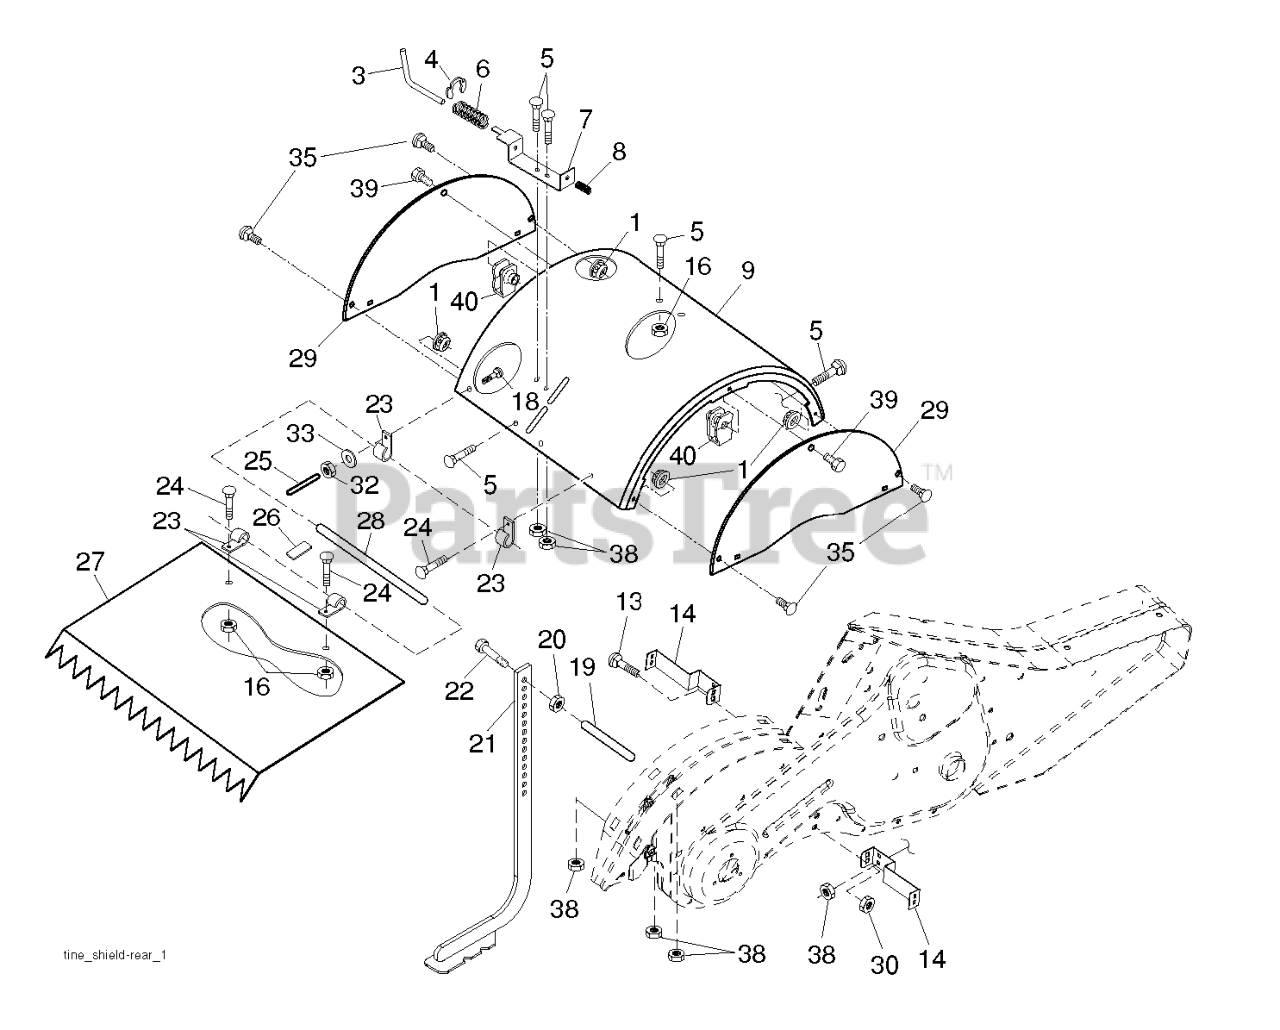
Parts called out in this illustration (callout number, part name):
1	NUT.FLANGE.5/16
3	STAKE PIN TI
4	RING, KLIP
5	BOLT, RDHD SQNK 5/16-18 X 3/4
7	BRACKET
8	SPRING CRT
9	SHIELD.TILLER.TINE.CRT14.ORNG
13	BOLT.CARRIAGE.5/16-18
14	BRACKET.TINE.SHIELD.BLACK
16	NUT T
20	NUT.HEX.3/8-16UNC
21	REPL BY 532 10 21-56
22	BOLT.375-16
25	VINYL CAP TI
26	PAD IDLER TI
27	SHIELD.PNT.LEVEL.CRT.14.ORANGE
28	PIN.HINGE.TILLER
29	SHIELD.TINE.SIDE.ORANGE
30	LOCKNUT-FLANGE 5/16-18
32	NUT
33	LOCKWASHER
35	BOLT.CARR.5/16-18X5/8.SHORT
38	NUT
39	BOLT.HEX.HD.WASHER.5/16-18X.75
40	NUT.SPEED.5/16-18
